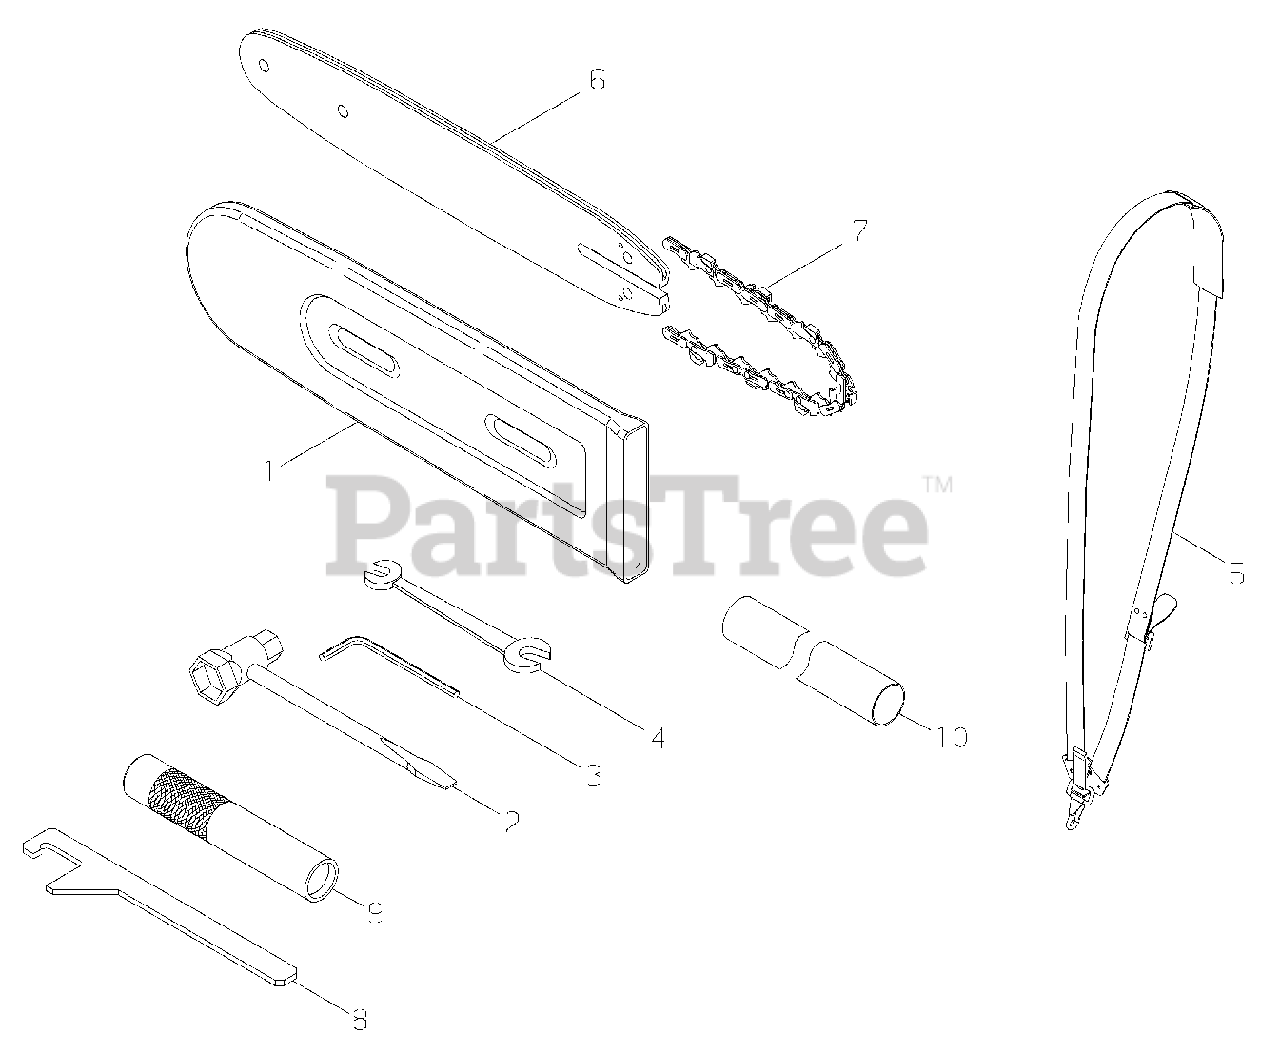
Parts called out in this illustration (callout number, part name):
2	T-WRENCH
3	WRENCH, ALLEN 4 MM
4	SPANNER 8×10
5	HARNESS ASSY, SHOULDER
6	GUIDE BAR, 8" MICROLITE FSN
6	GUIDE BAR, 10"
6	GUIDE BAR - 12"
7	SAW CHAIN 8" 3/8" 0.043 90SG-033X
7	SAW CHAIN 10" 3/8" 0.043 90SG-039X
7	SAW CHAIN 12" 3/8" 0.043 90SG-044X
8	HOOK, SPANNER
10	COLLAR
